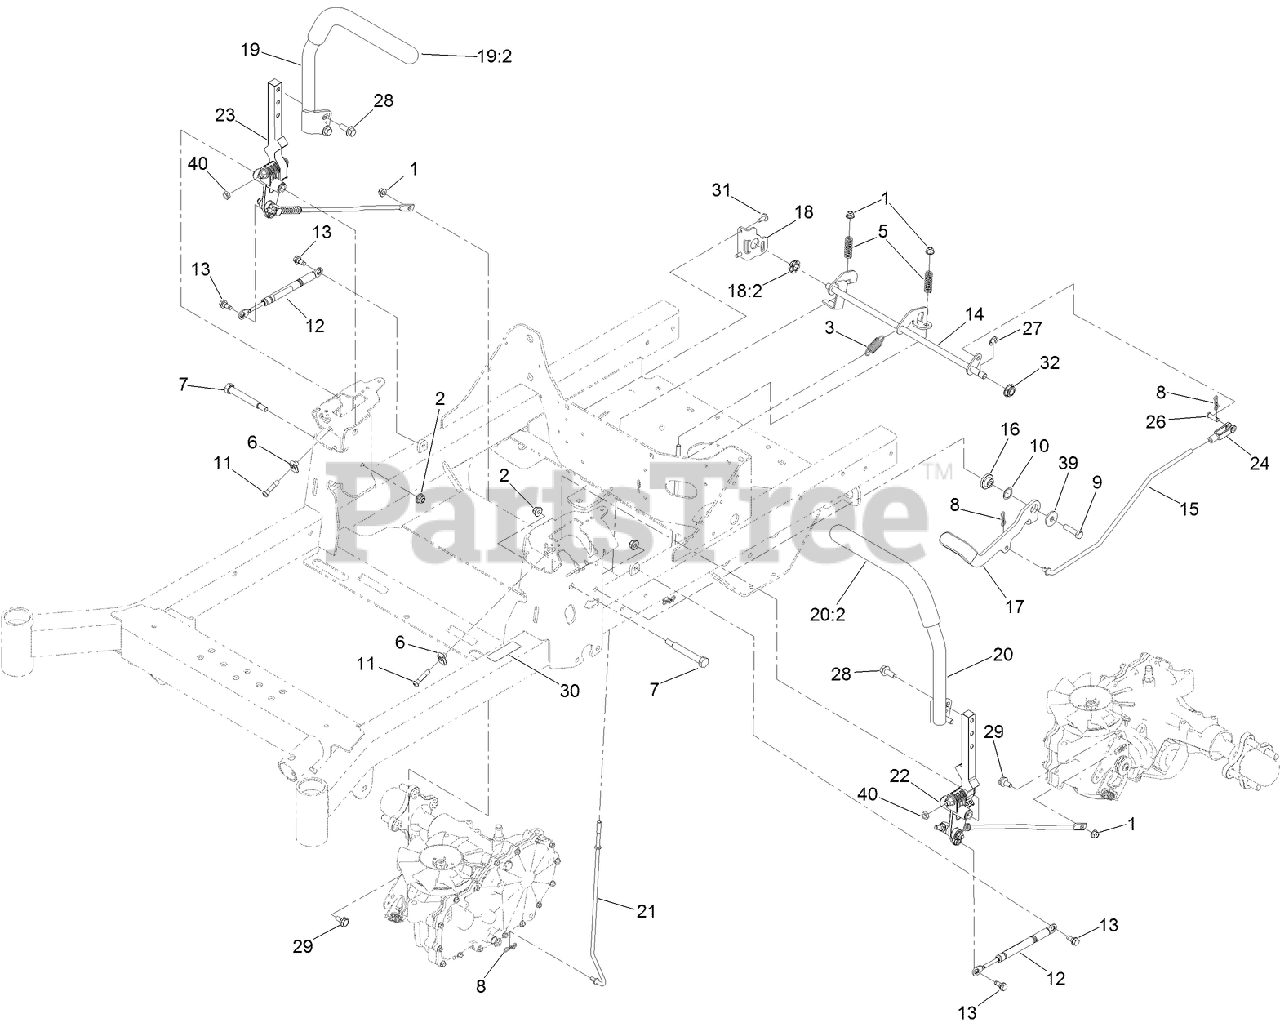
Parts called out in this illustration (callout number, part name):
1	NUT-HF, NI
2	NUT-HF, NI
3	SPRING-EXTENSION
5	SPRING-COMPRESSION
7	BOLT-PIVOT
8	PIN-COTTER, LOCKING
9	SCREW-HH
10	WASHER-WAVE
11	SCREW-HSBH
12	DAMPER
13	SCREW-SHOULDER
14	SHAFT-BRAKE
15	LINKAGE-BRAKE, UPPER
16	PIVOT-FLANGE
17	LEVER-BRAKE (WITH GRIP)
18	BRACKET-BRAKE
18:2	BEARING-SPHERICAL
19	RH CONTROL HANDLE ASM
20	LH CONTROL HANDLE ASM
21	LINKAGE-BRAKE, LOWER
22	HUB and BEARING ASM
23	HUB and BEARING ASM
24	YOKE-ADJUSTABLE
26	PIN-CLEVIS
27	RING-RETAINING, EXTERNAL
28	SCREW-HHF
29	BOLT-SHOULDER,HFH
30	DECAL-BRAKE, PARKING
31	SCREW-TORX
32	BEARING-SPHERICAL
39	WASHER
40	NUT-JAM
